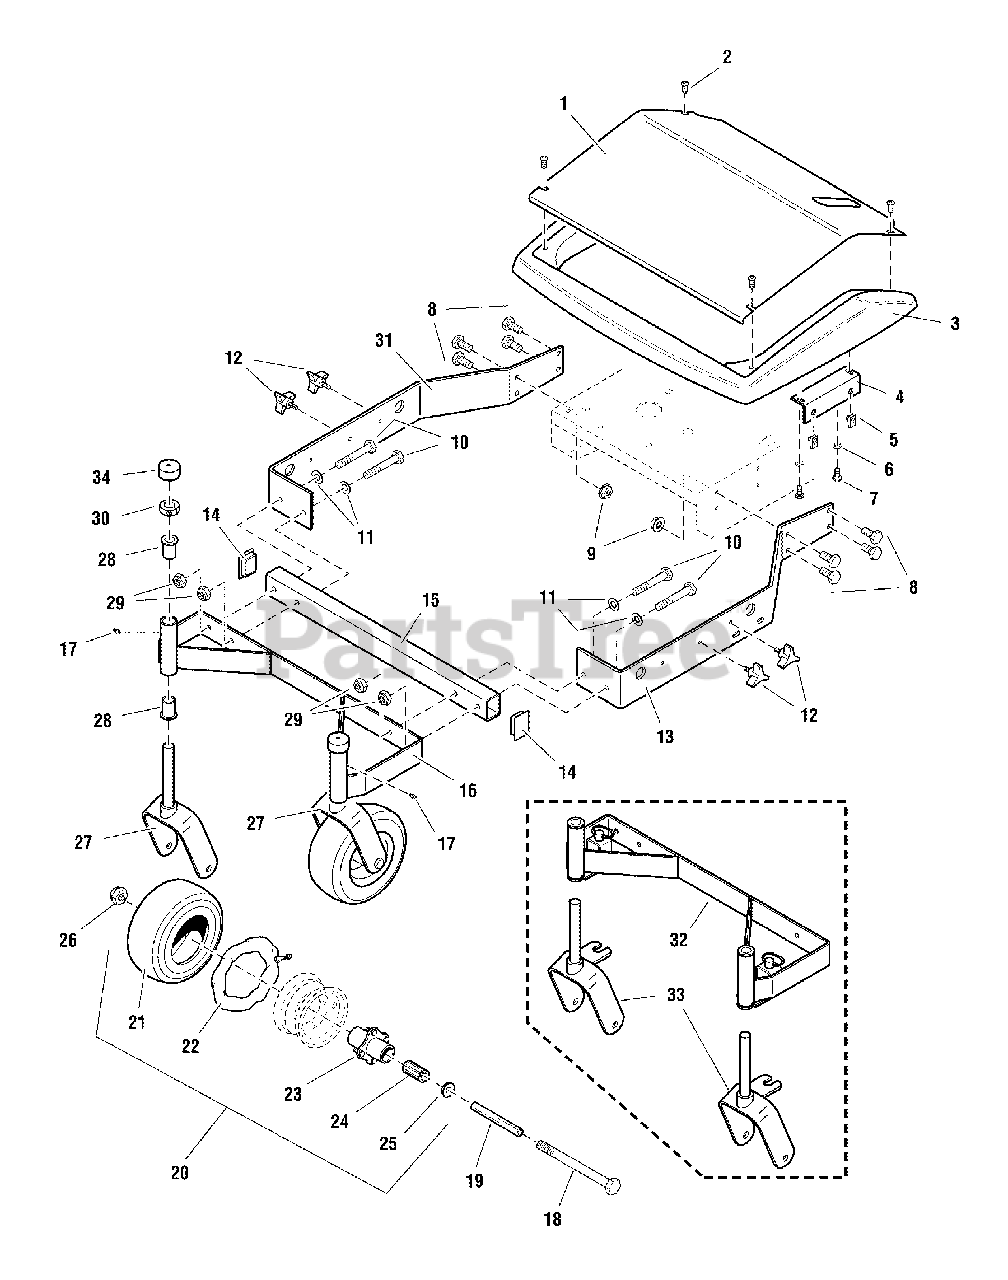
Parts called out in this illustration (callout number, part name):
1	SHIELD INSERT
2	SCREW, Allen Head, 1/4-20 x 1/2
3	GUARD, MOWER HOUSING
4	SHIELD MOUNT BRACKET
5	BODY CLIP, 5/16-18
6	WASHER, 1/4" Lock
7	BOLT, 1/4-20 x 3/4
8	BOLT, 3/8-16 X 1" GD5 CZ
9	NUT, 3/8-16 Hex Serrated Flange
10	BOLT, 3/8-16 X 2-1/2" GD5 CZ
11	WASHER, 3/8 SAE
12	KNOB
13	FRAME RAIL - LH
14	CAP, Plastic
15	CROSS TUBE
16	CASTER MOUNT FRAME, Complete
17	GREASE FITTING
18	BOLT, 1/2-13 x 5-1/2
19	AXLE, Caster Wheel
20	WHEEL & TIRE ASSEMBLY, Silver, 9 x 3.5 x 4, Complete
21	TIRE, Front, 9 x 3.5 x 4
22	TUBE
23	HUB & BEARING ASSEMBLY, Complete, Silver
24	BEARING, ROLLER 3/4" ID X 3.25" (ONE PER TIRE)(SV)
25	RETAINER, Bearing
26	NUT, 1/2-13 Hex Nylon Lock
27	CASTER YOKE
28	BUSHING, Flange
29	NUT, 3/8-16 Hex Nylon Lock
30	COLLAR, 3/4" Split
31	FRAME RAIL - RH
32	CASTER MOUNT FRAME W/ LOCKS, Complete
33	CASTER YOKE
34	CAP,VINYL, 1.375 X 1
